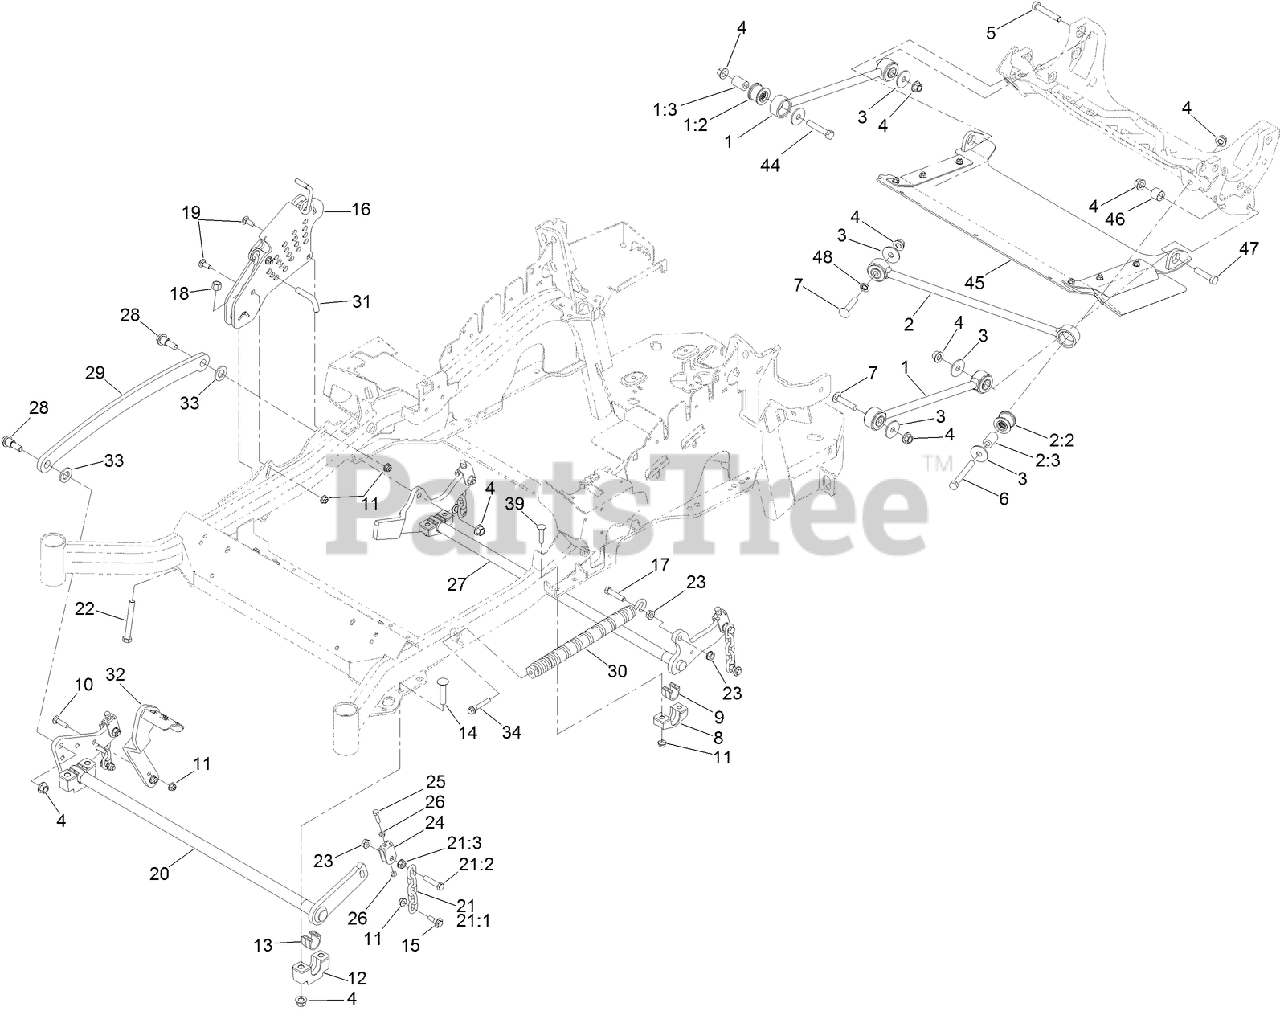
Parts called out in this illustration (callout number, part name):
1	DECK STRUT ASM
1:2	BUSHING-SUSPENSION, RUBBER
1:3	SPACER
2	PANHARD ROD ASM
2:2	BUSHING-SUSPENSION, RUBBER
2:3	SPACER
3	WASHER-THRUST
4	NUT-LOCK
5	SCREW-HH
6	SCREW-HH
7	SCREW-CARR
8	SUPPORT-CROSS SHAFT, REAR BEARING
9	BEARING-CROSS SHAFT, REAR
10	SCREW-CARR
11	NUT-HF, NI
12	SUPPORT-CROSS SHAFT, BEARING
13	BEARING-CROSS SHAFT, FRONT
14	BOLT-CARR
15	SCREW-SHOULDER, HHF
16	HOC ASM
17	SCREW-HH
18	NUT-LOCK, NI
19	BOLT-CARR
20	DECKLIFT-FRONT
21	DECK LIFT CHAIN ASM
21:1	CHAIN-LIFT, DECK
21:2	SCREW-HH
21:3	NUT-HF
22	BOLT-TAP
23	NUT-HF
24	YOKE-ADJUST, DECK
25	SCREW-HH
26	NUT-JAM
27	LIFT-DECK, REAR
28	SCREW-SHOULDER, HHF
29	LINK-LIFT, DECK
30	SPRING-EXTENSION
31	PIN-HOC
32	LEVER-FOOT
33	WASHER-FLAT
34	BOLT-SHOULDER
39	SCREW-CARR
44	SCREW-HH
45	DISCHARGE TUNNEL ASM
46	BUSHING-SLEEVE
47	SCREW-HH
48	NUT-PUSH
